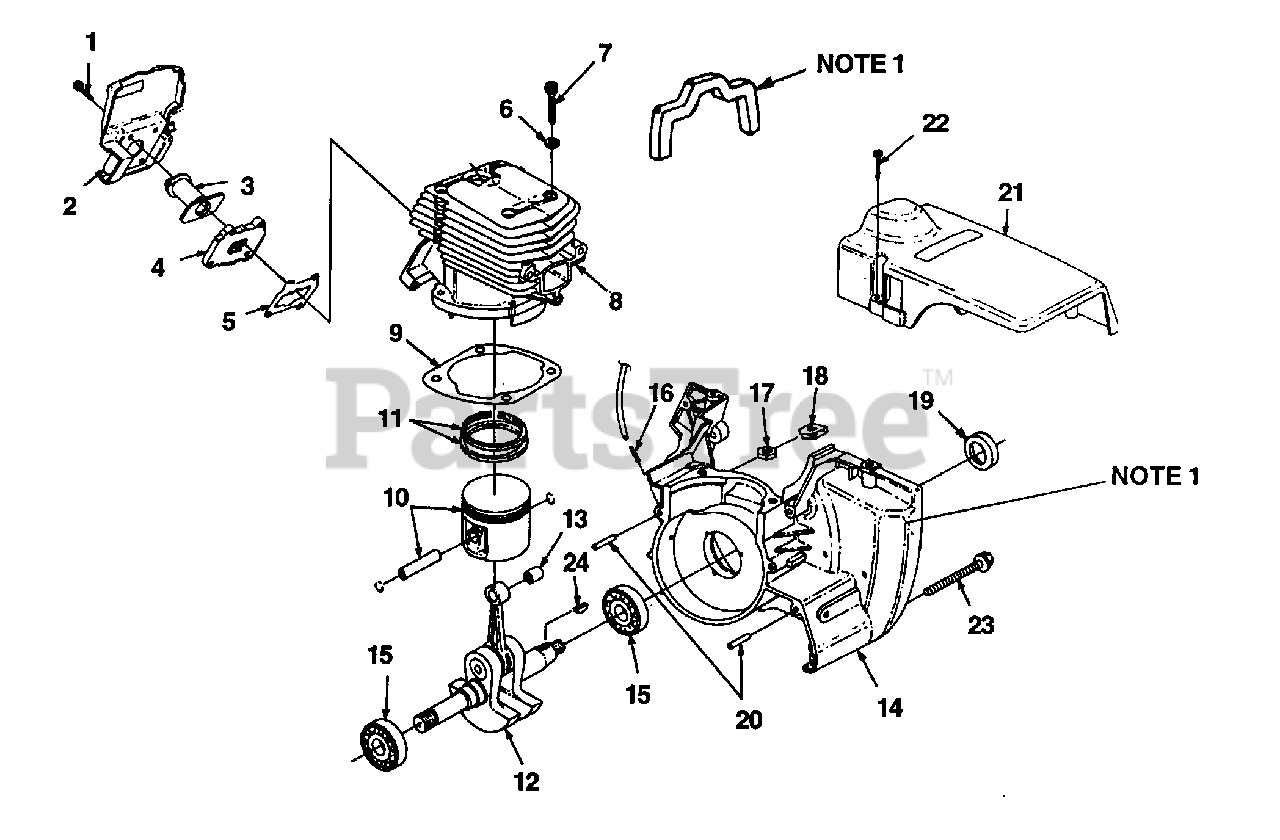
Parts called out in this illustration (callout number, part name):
1	SCREW - Mach. Hex Hd. (10-24 X 1")
2	BAFFLE - Cylinder
3	BOOT - Intake
4	ADAPTER - Intake
5	GASKET - Intake
6	WASHER - Conical (#10)
7	SCREW - Cap Socket (10-24 X 1")
8	CYLINDER & PISTON (Matched)
9	GASKET - CYLINDER
10	PISTON & PIN ASSY.
11	PISTON RING
12	CRANKSHAFT & ROD
13	BEARING - Needle
14	CRANKCASE ASSY.
15	BEARING - Ball
16	FITTING - Tube
17	NUT - Lock Hex (10-24)
18	NUT - Retainer
19	SEAL - Shaft
20	PIN - Dowel
21	COVER - CYLINDER
22	SCREW - CYLINDER COVER
23	SCREW - Hex Sems (10-24 X 2")
24	KEY - Woodruff
